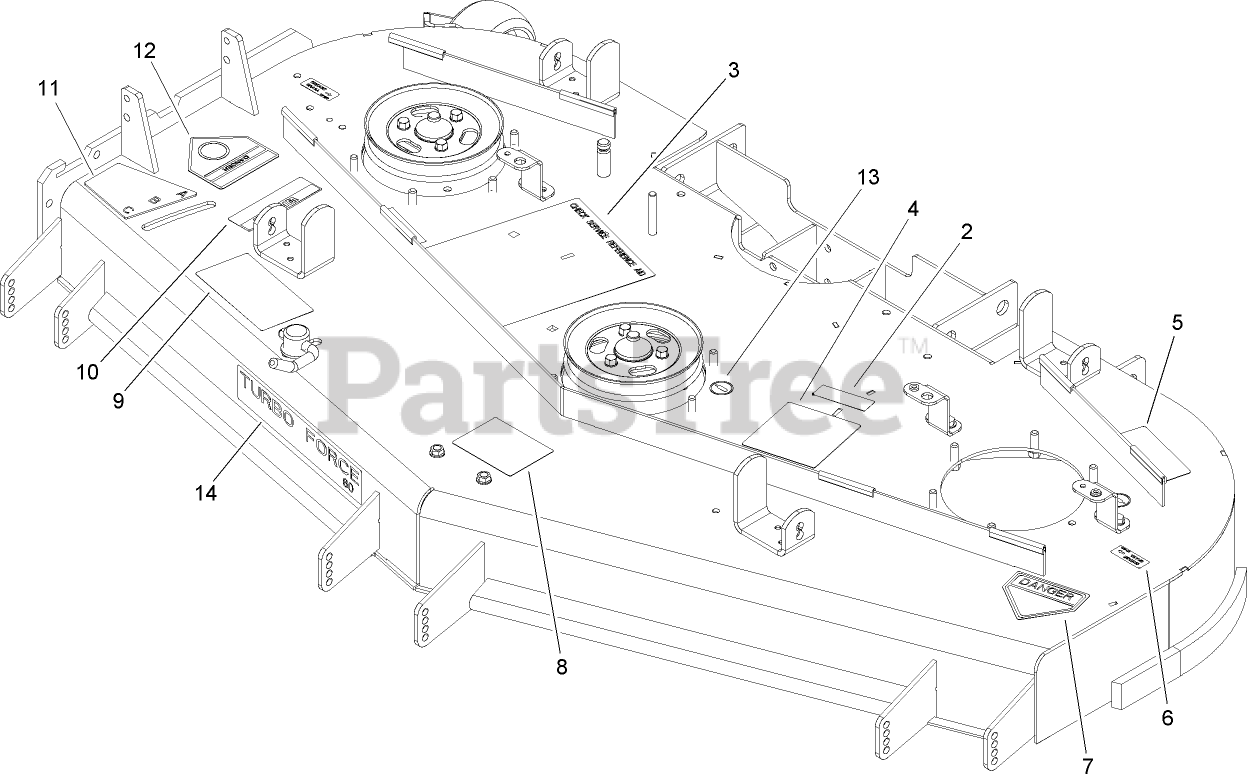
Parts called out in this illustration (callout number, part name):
2	DECAL-COVER, MISSING
3	DECAL-CHECK, SERVICE
4	DECAL-ROUTING, BELT
5	DECAL-TORQUE
6	Decal-Grease
7	DECAL-DANGER
8	DECAL-SCALP, ANTI
9	DECAL-DANGER, THROWN OBJECT
10	DECAL-WARNING
11	DECAL-ADJUSTMENT, BAFFLE
12	DECAL-DANGER
13	DECAL-GREASE
